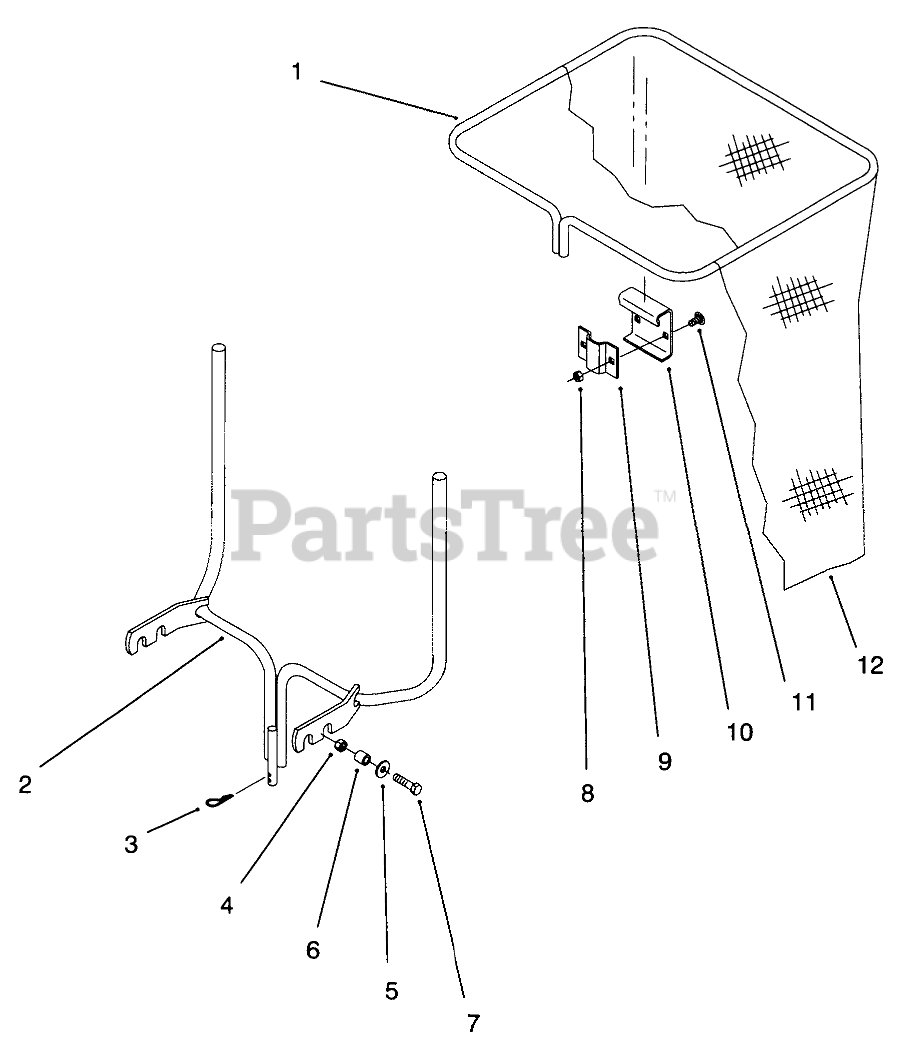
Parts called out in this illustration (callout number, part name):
1	Bag Frame
2	Panel-Front
3	PIN-COTTER, HAIR
4	NUT-LOCK, NI
5	Washer
6	SPACER
7	SCREW-HH
8	NUT-LOCK, NI
9	Clamp
10	Bag Hanger
11	BOLT-CARR
12	BAG-DEPTH
